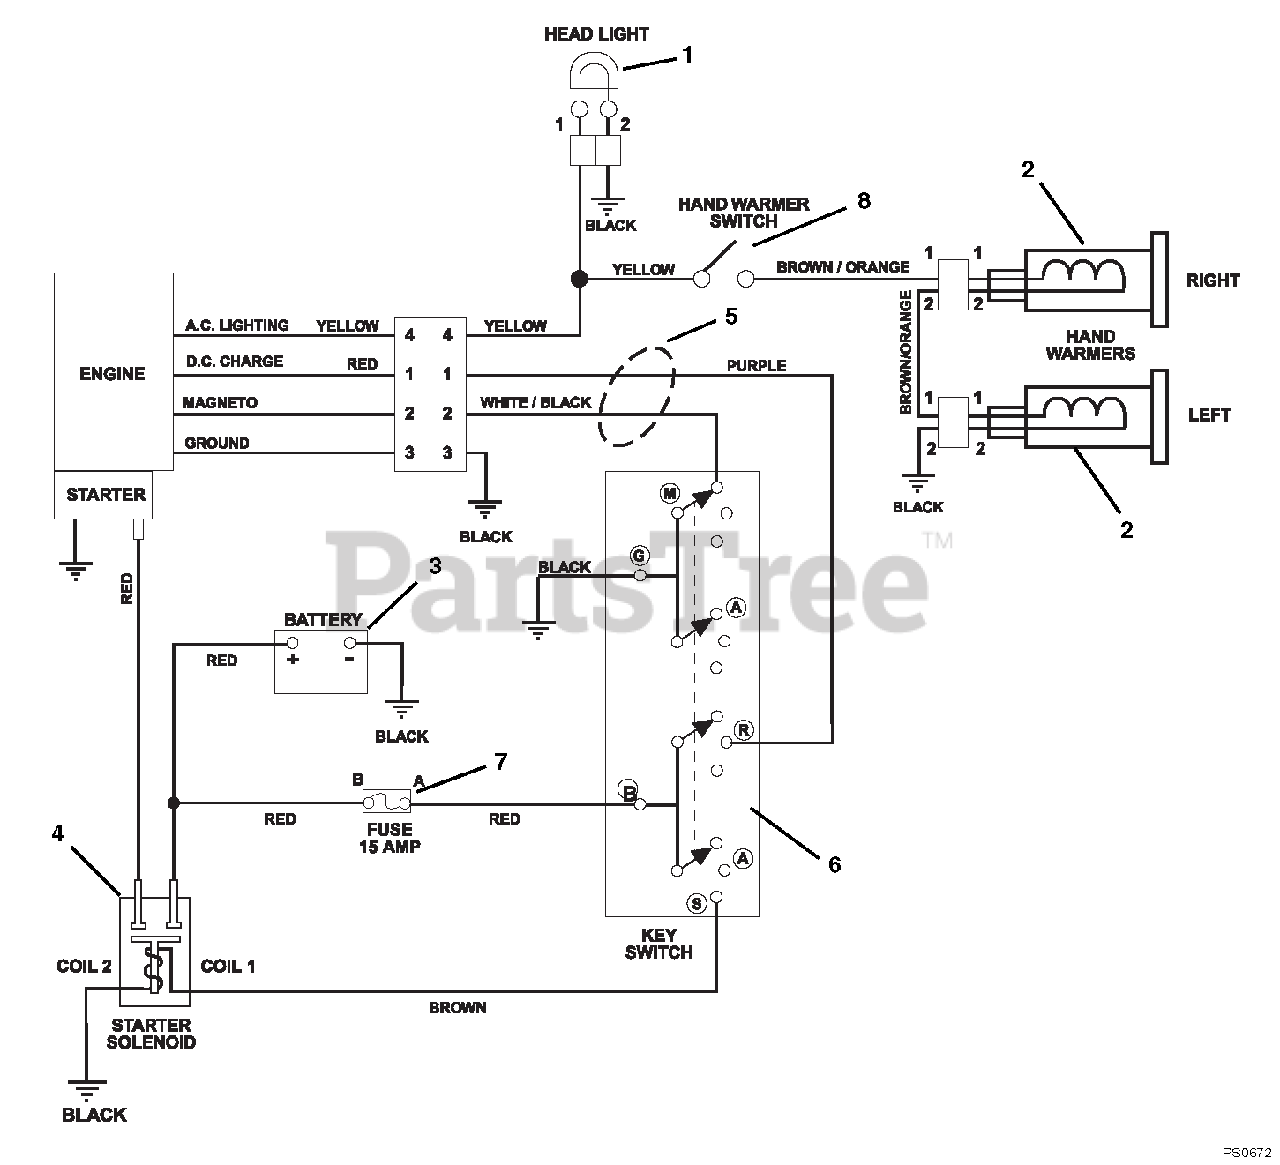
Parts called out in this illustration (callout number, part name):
1	LIGHT, HALOGEN ASSY.
2	HEATED GRIP, MAGURA
4	SOLENOID
5	HARNESS, WIRE-LT, HW, & 12V
6	SWITCH ASSEMBLY
7	FUSE, 15 AMP.
8	SWITCH, ON/OFF
